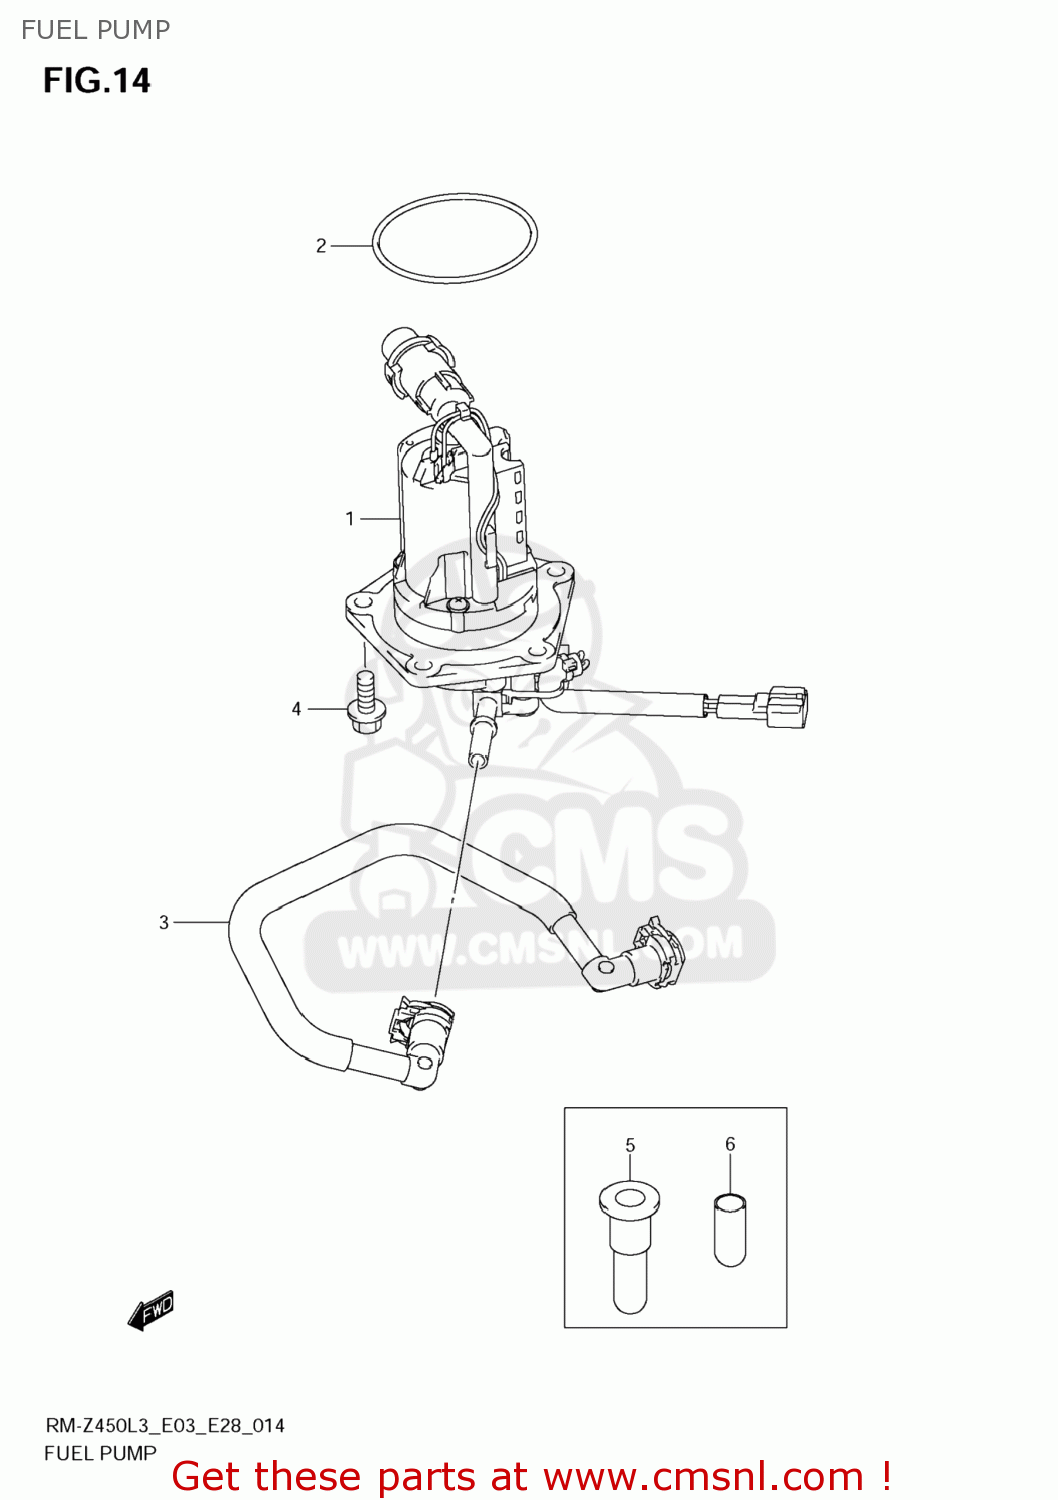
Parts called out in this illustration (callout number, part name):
1	PUMP ASSY,FUEL
2	O RING
3	HOSE,FUEL
4	BOLT
5	CAP,FUEL HOSE
6	CAP,FUEL PUMP
